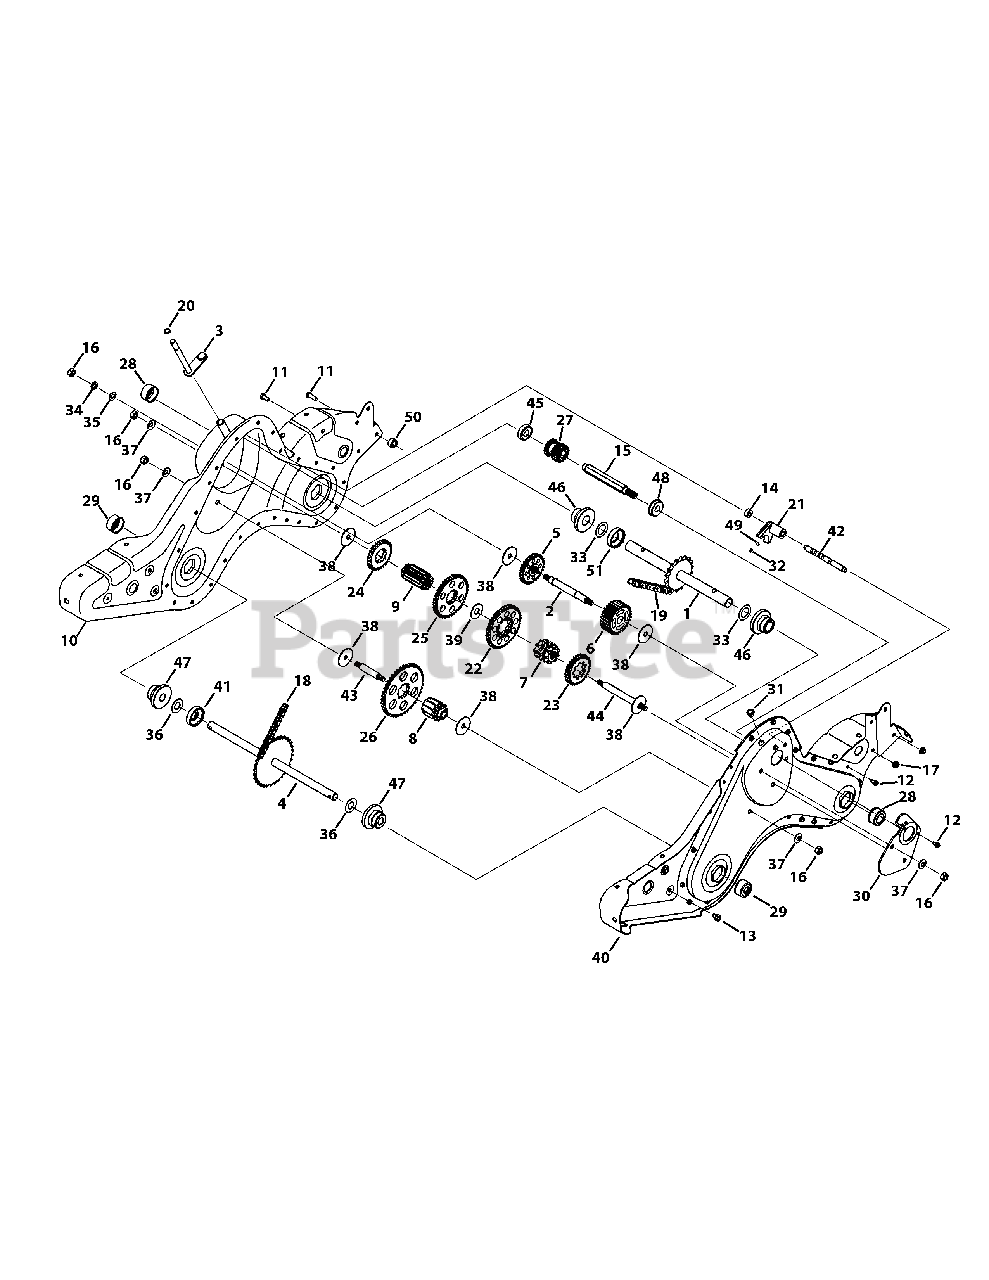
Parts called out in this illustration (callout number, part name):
1	Tine Shaft Assembly
2	Jack Shaft Assembly
3	Shif Input Shaft Assembly
4	Wheel Shaft Assembly, 33T
5	Reverse Idler Gear Assembly, 30T
6	Tine Idler Gear Assembly, 30T
7	Tine Input Sprocket Assembly, 9T
8	Wheel Input Sprocket Assembly, 10T
9	Gear Assembly, 11T
10	RH Chain Case Housing Assembly
11	Hex Head Screw, 5/16-18 x 1.00
12	Hex Washer Screw, 1/4-20 x .625
13	Hex Washer Screw, 5/16-18 x .750
14	Spacer, .505 x .88 x .440
15	Input Shaft, .75
16	Hex Nut, 7/16-20
17	Flange Lock Nut, 5/16-18
18	Endless Chain, #420 x 50
19	Endless Chain, #50 x 54
20	Snap Ring, .500
21	Clutch Collar
22	Gear Spur, 44T
23	Gear Spur, 30T
24	Gear Spur, 30T
25	Gear Spur, 44T
26	Gear Spur, 44T
27	Gear Spur, 16T
28	Shaft Seal, 1.0
29	Shaft Seal, .75
30	Positioner Gear Bracket
31	Tapered Cap Plug
32	Compression Spring, .230
33	Flat Washer, 1.03 x 1.62 x .03
34	Lock Washer, 7/16
35	Flat Washer,.474 x .879 x .064
36	Flat Washer, .760 x 1.50
37	Bell Washer, .45 x 1.00 x .062
38	Thrust Washer, .445 x 1.92 x .060
39	Flat Washer, 1.595 x .635 x .062
40	LH Chain Case Housing
41	Spacer, .75 x 2.0 x .50
42	Shaft Detent, .5 DIA
43	Jack Shaft, .625 x 2.385
44	Jack Shaft, .6250 x 5.0050
45	Ball Bearing, 17 x 40 x 12
46	Flange Bearing, 1.0 x 2.5 x 1.38
47	Flange Bearing, .75 x 2.5 x 1.38
48	Ball Bearing, 17 x 40 x 12:6203
49	Detent Ball, .250
50	Spacer, .315 x .750 x .375
51	Spacer, 1.0 x 2.0 x .5
